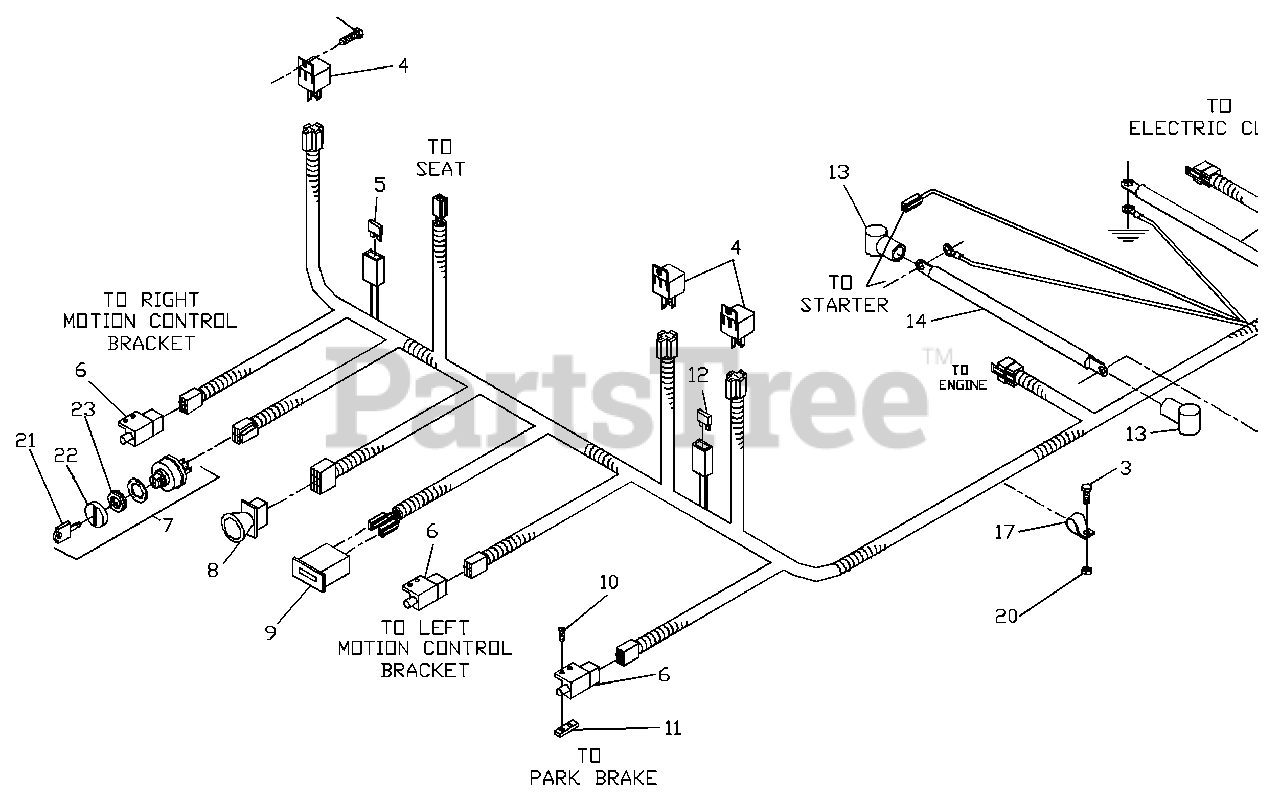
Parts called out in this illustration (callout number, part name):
1	WIRING HARNESS
2	#10 X 1/2 HEX SELF-TAPPING SCREW
3	1/4C X 3/4 HEX CAP SCREW
5	7.5 AMP 32 VOLT ATO FUSE
6	INTERLOCK SWITCH
7	IGNITION SWITCH W / KEY
8	BLADE SWITCH
9	HOUR METER
10	#10-24 X 5/8 SLOTTED SCREW
11	TAPPED PLATE
12	20 AMP 32 VOLT ATO FUSE
14	POSITIVE (+) BATTERY CABLE (RED)
15	NEGATIVE (-) BATTERY CABLE (BLACK)
16	12 VOLT 330 AMP BATTERY
18	5/16C CENTERLOCK NUT
19	5/16C X 1 HEX CAP SCREW
20	1/4C CENTERLOCK NUT
21	KEY, PADDED
